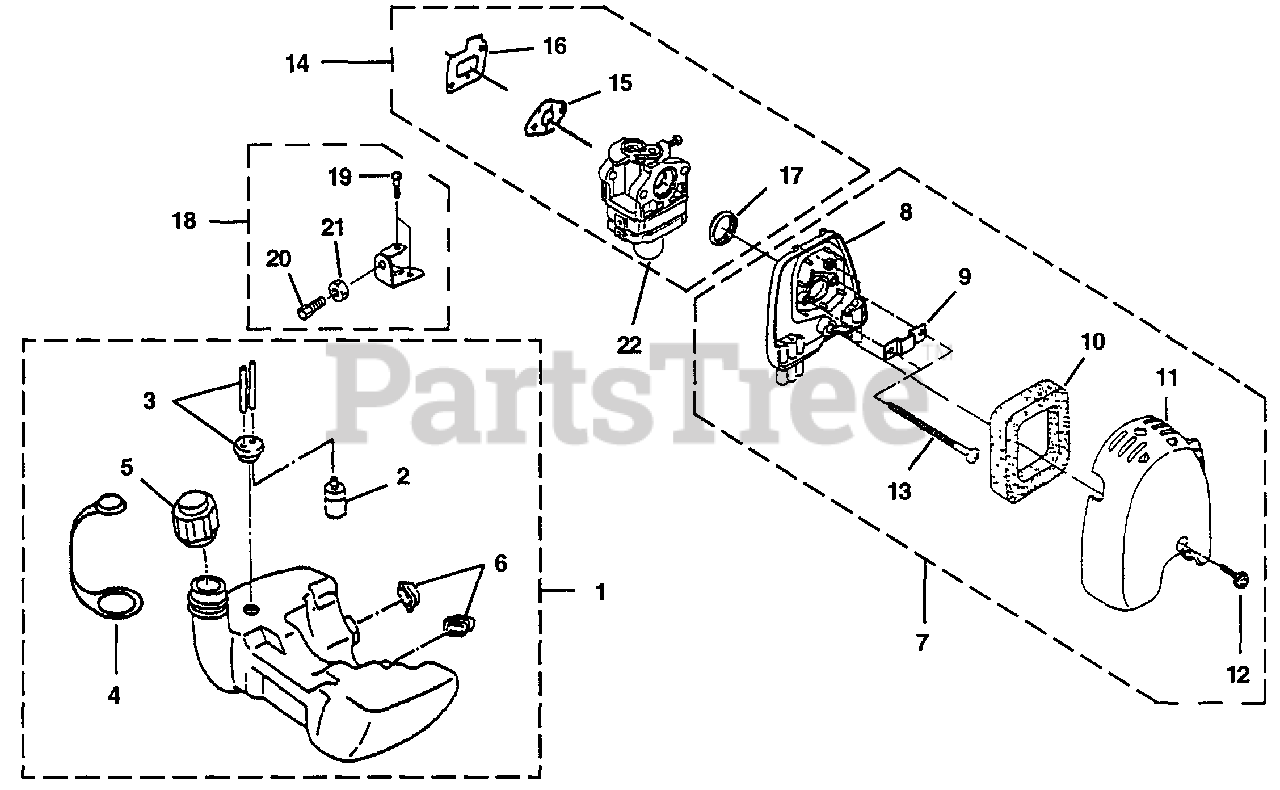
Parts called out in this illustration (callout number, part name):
1	FUEL TANK ASSEMBLY
2	FILTER-Fuel
4	CAP-Retainer
5	CAP-Fuel
6	RUBBER BUMPER KIT
7	AIR FILTER ASSEMBLY
8	PLATE-Air Filter Assembly
9	PLATE-Air Filter
10	FILTER-Air
11	COVER-Air Filter
12	SCREW ASSEMBLY (M5 x 14)
14	CARBURETOR ASSEMBLY
15	GASKET-Carburetor
16	GASKET-Heat Dam
17	RING-Packing
18	CABLE BRACKET ASSEMBLY
19	SCREW-Throttle Collar
20	SCREW-Cable Adjust
21	NUT-Cable Adjust
22	PRIMER BULB
